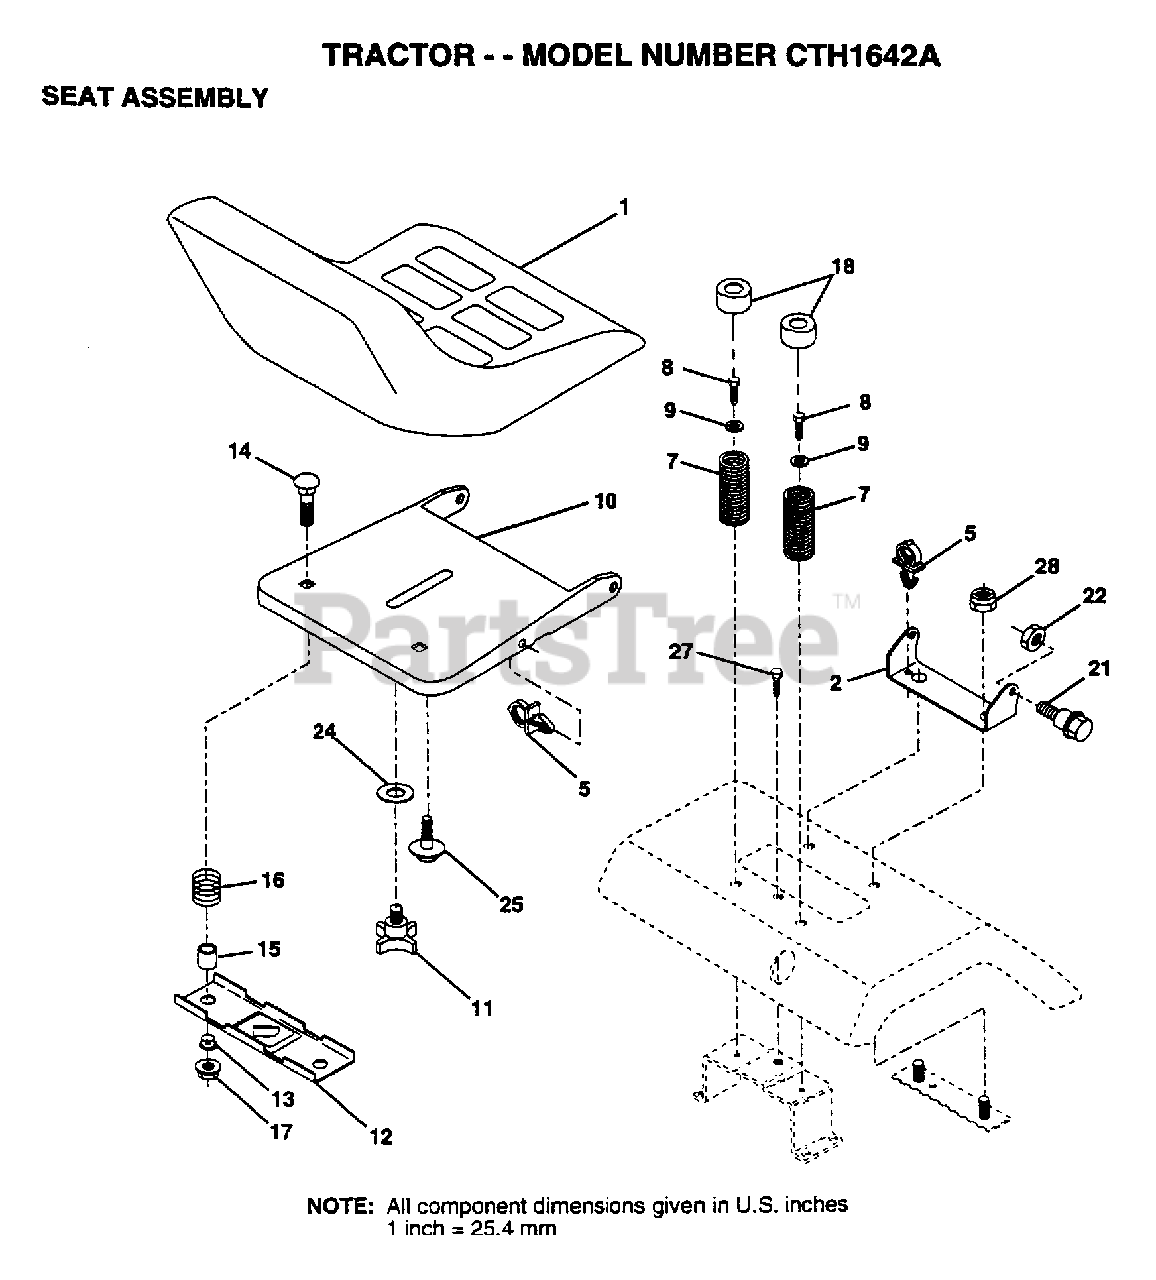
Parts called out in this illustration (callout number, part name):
2	BRACKET PVT SEAT
5	CLIP.PUSH-IN.HING
7	SPRING COMPRESSIO
8	SCREW LT
9	WASHER
11	"KNOB 1/2"" YT"
12	BRKT SWITCH
13	BUSHING
15	SPACER SPLIT
16	SPRING COMPRESSED
18	CAP SPRING
21	BOLT.SHLD.5/16-18
24	WASHER
25	"BOLT,SHOULDER"
27	SCREW LT
